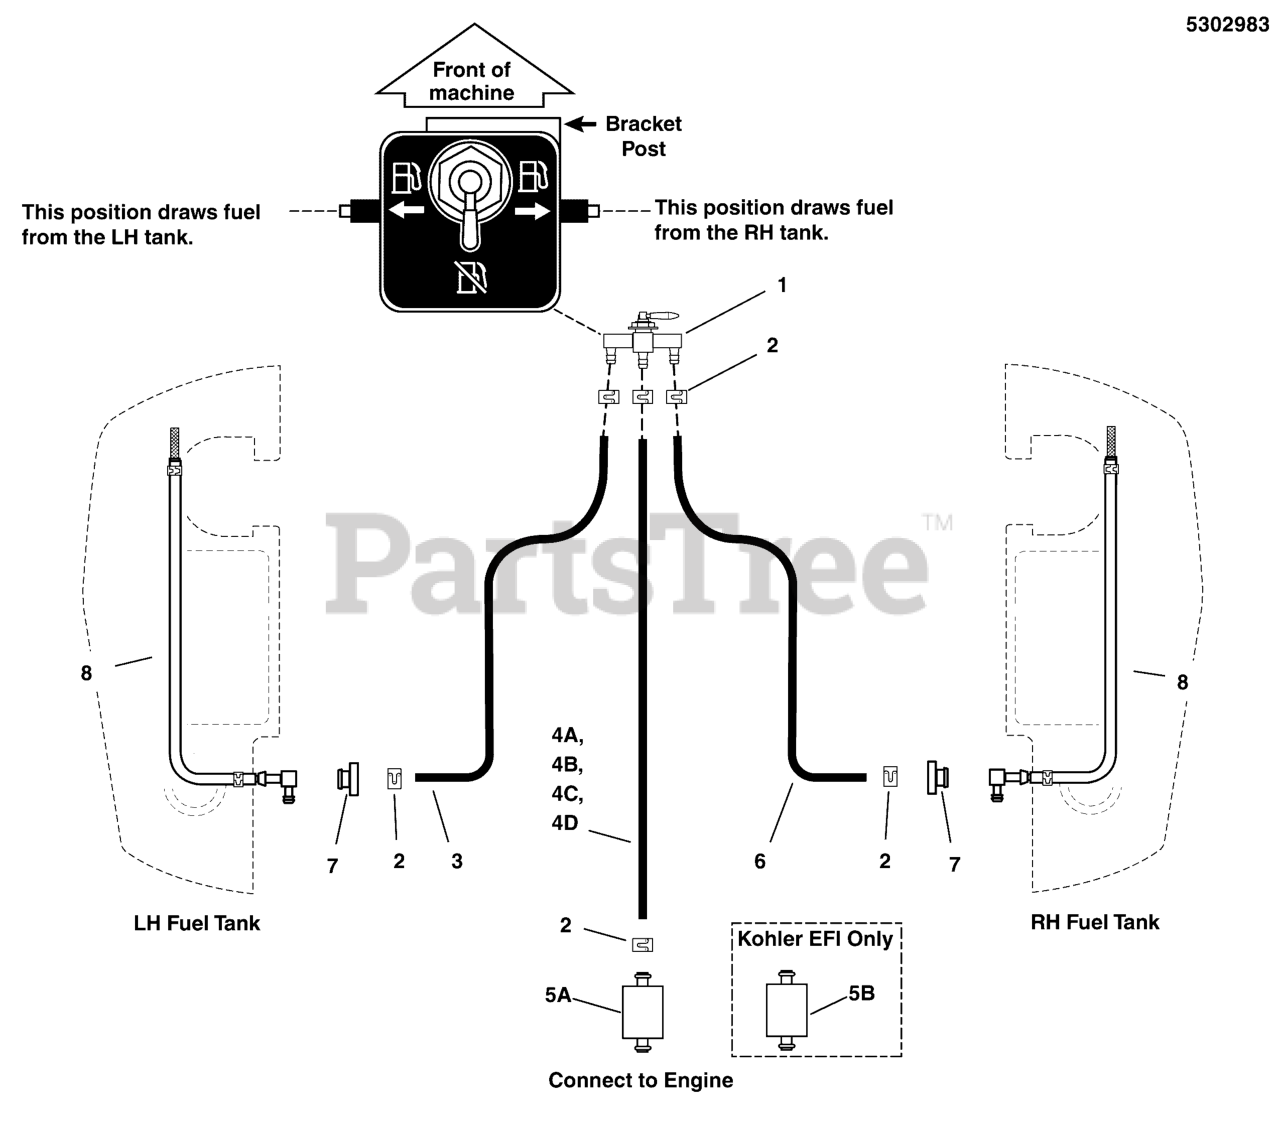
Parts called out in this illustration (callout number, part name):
1	VALVE, FUEL, STR. OUTLET
2	CLAMP, HOSE, EXTERNAL, 1/2 - RED
3	HOSE, 1/4" FUEL, 31.00"
6	HOSE, 1/4" FUEL, 10.00"
7	BUSHING-FUEL TANK RED RUBBER
8	HOSE ASSEMBLY
